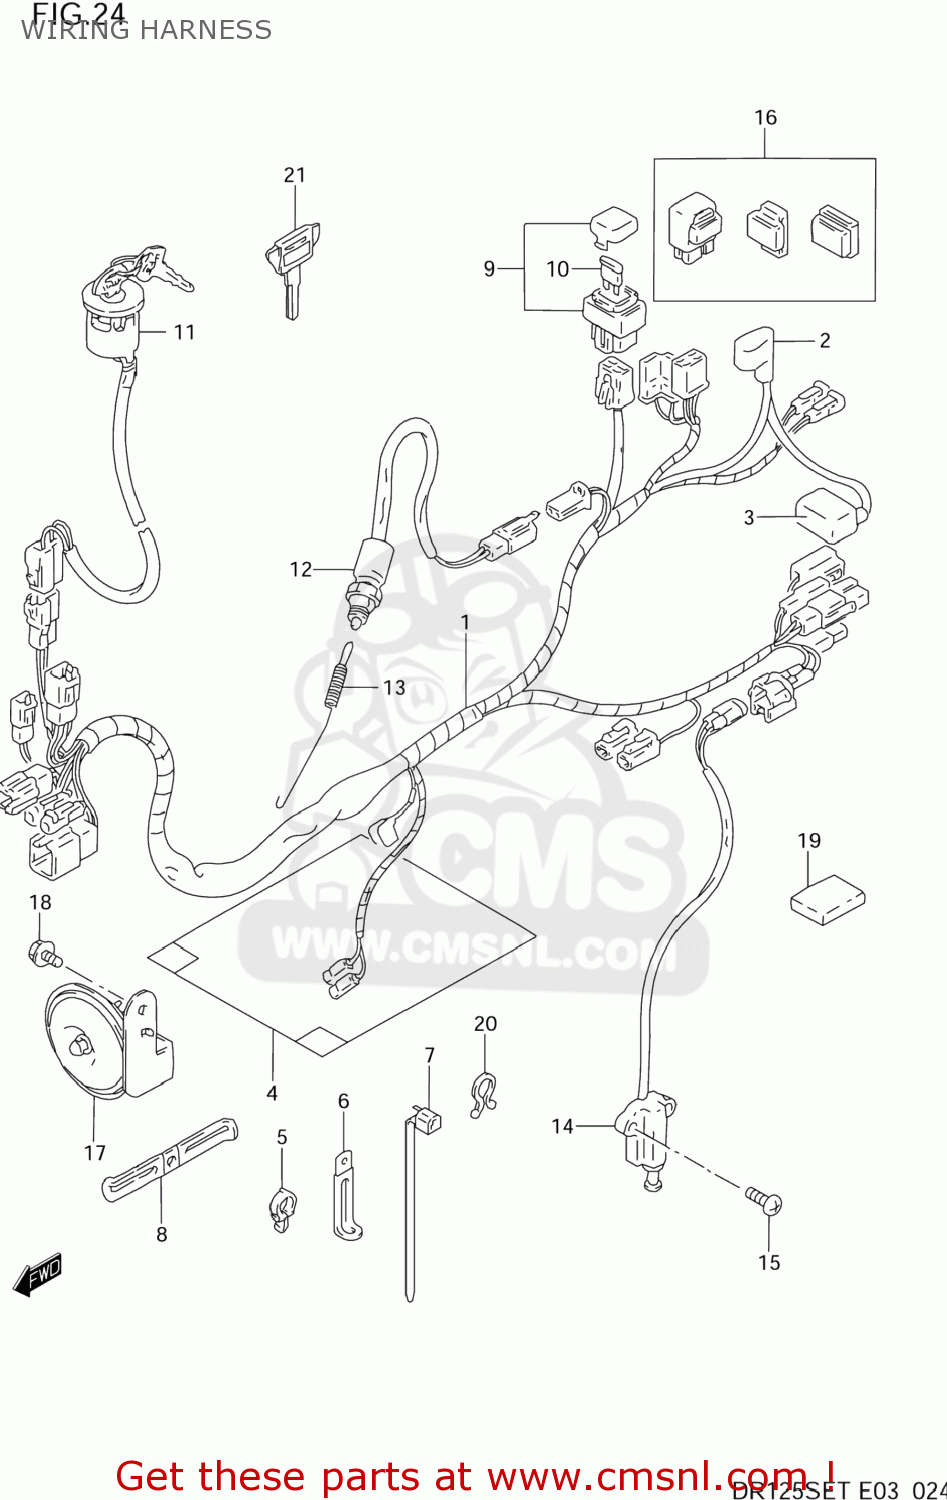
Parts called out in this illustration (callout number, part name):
1	HARNESS,WIRING
2	CAP,STARTER RELAY
3	CAP,BATTERY PLUS
4	COVER,WIRING HARNESS
5	CLAMP
6	CLAMP
7	CLAMP
8	CLAMP,STARTER MOTOR LEAD
9	BOX ASSY,FUSE
10	FUSE(20A)
11	SWITCH ASSEMBLY,IGNITION
12	SWITCH ASSY,STOP LAMP
13	SPRING
14	SWITCH ASSY,SIDE STAND
15	SCREW
16	RELAY ASSY
17	HORN ASSY
18	BOLT
19	PROTECTOR,WIRING HARNESS
20	CLIP(ID:11.5)
21	KEY,BLANK(TYPE:C)
